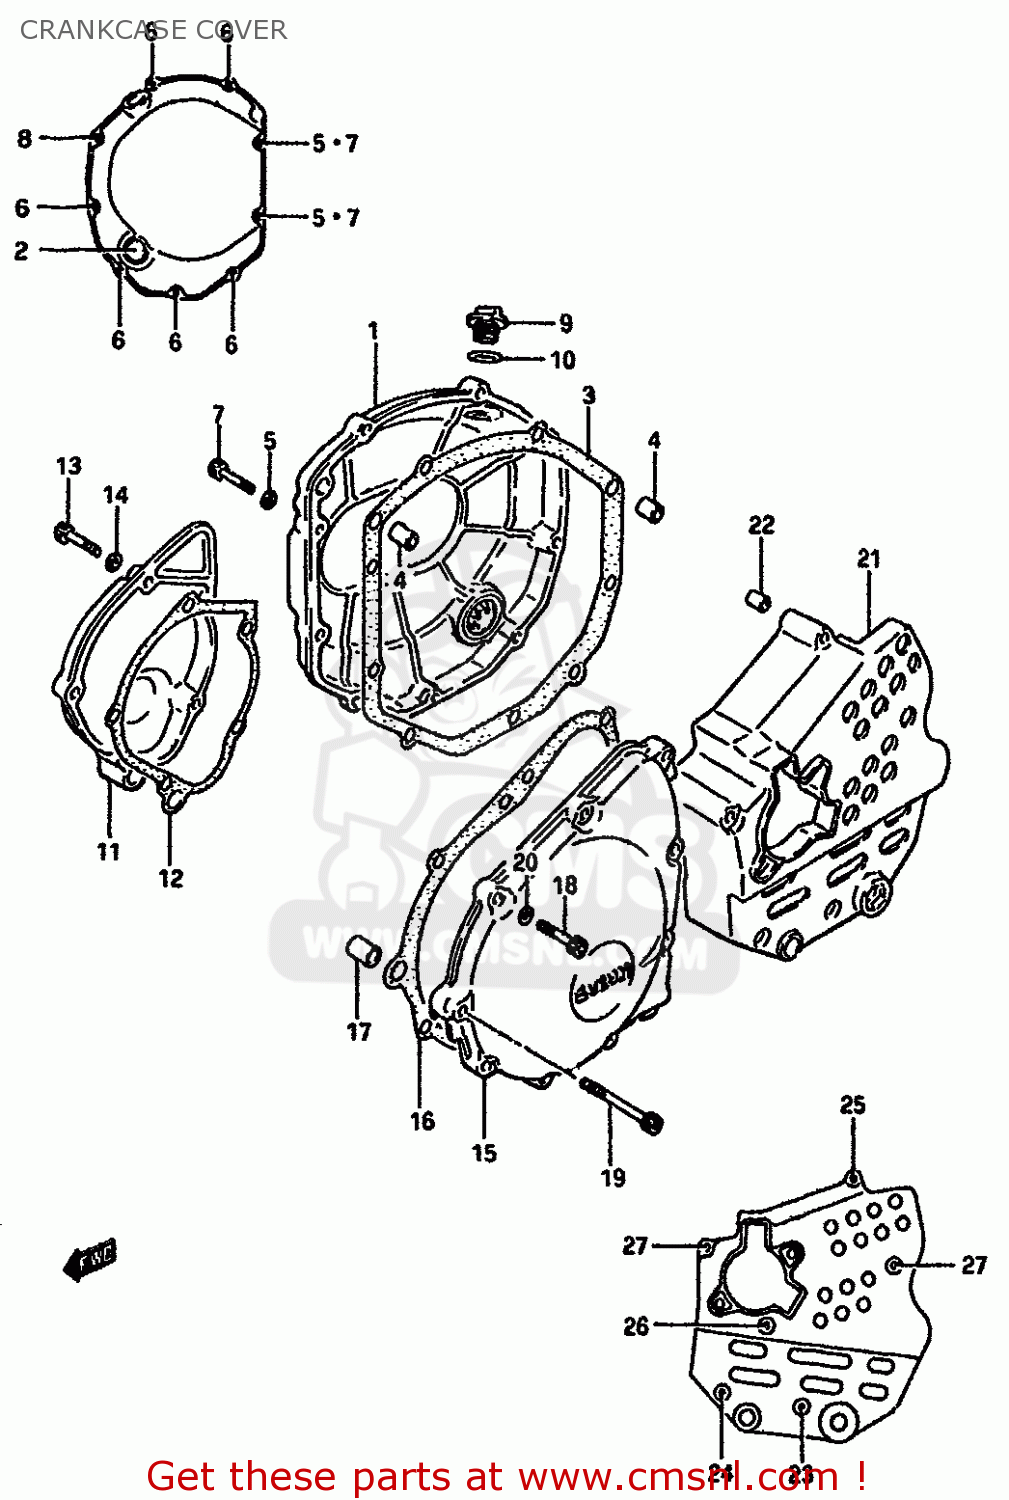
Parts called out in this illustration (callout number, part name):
1	COVER,CLUTCH
2	LENS,OIL LEVEL CHECK
3	GASKET,CLUTCH COVER (MCA)
4	PIN
5	GASKET(5.8X11X1.2) (NAS)
6	BOLT
7	BOLT
8	BOLT
9	PLUG
10	O RING(D:3.1,ID:16.8)
11	COVER,SIGNAL GENERATOR
12	GASKET,SIGNAL GENERATOR COVER (NAS)
13	BOLT
14	GASKET(5.8X11X1.2) (NAS)
15	COVER,STARTER GEAR
16	GASKET,STARTER GEAR COVER (MCA)
17	PIN (11X20)(SUS)
18	BOLT
19	BOLT
20	GASKET(5.8X11X1.2) (NAS)
21	COVER,SPROCKET
22	PIN
23	BOLT
24	BOLT
25	BOLT
26	BOLT
27	BOLT
